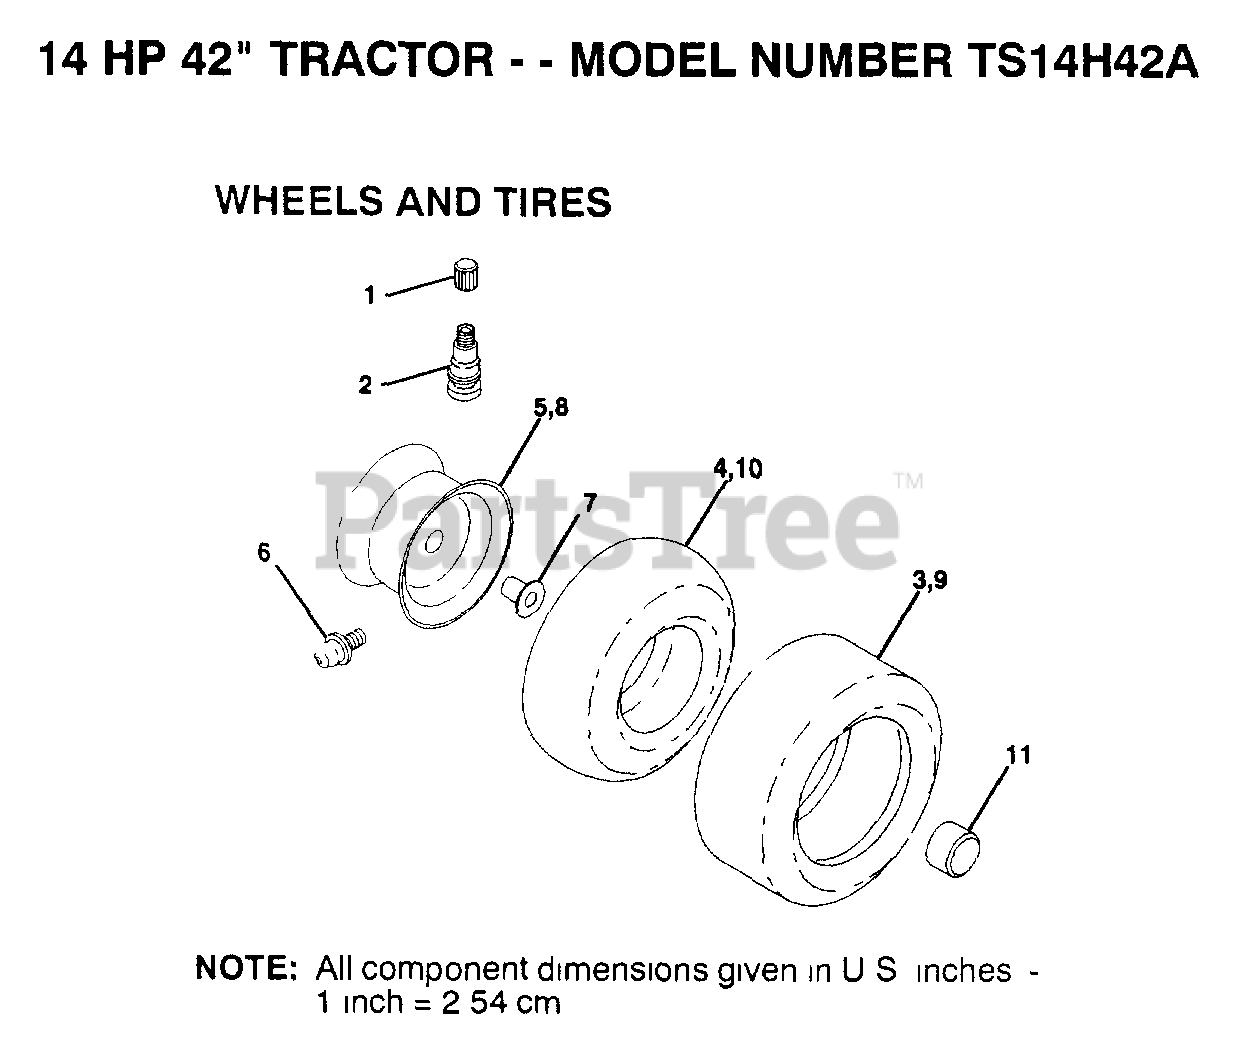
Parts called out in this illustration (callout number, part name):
1	VALVE CAP
2	VALVE STEM LT
4	TUBE.5.3/4.5/6
6	FITTING LT
7	"FLANGE, BEARING"
10	TUBE.18X9.5-8
11	HUB CAP
